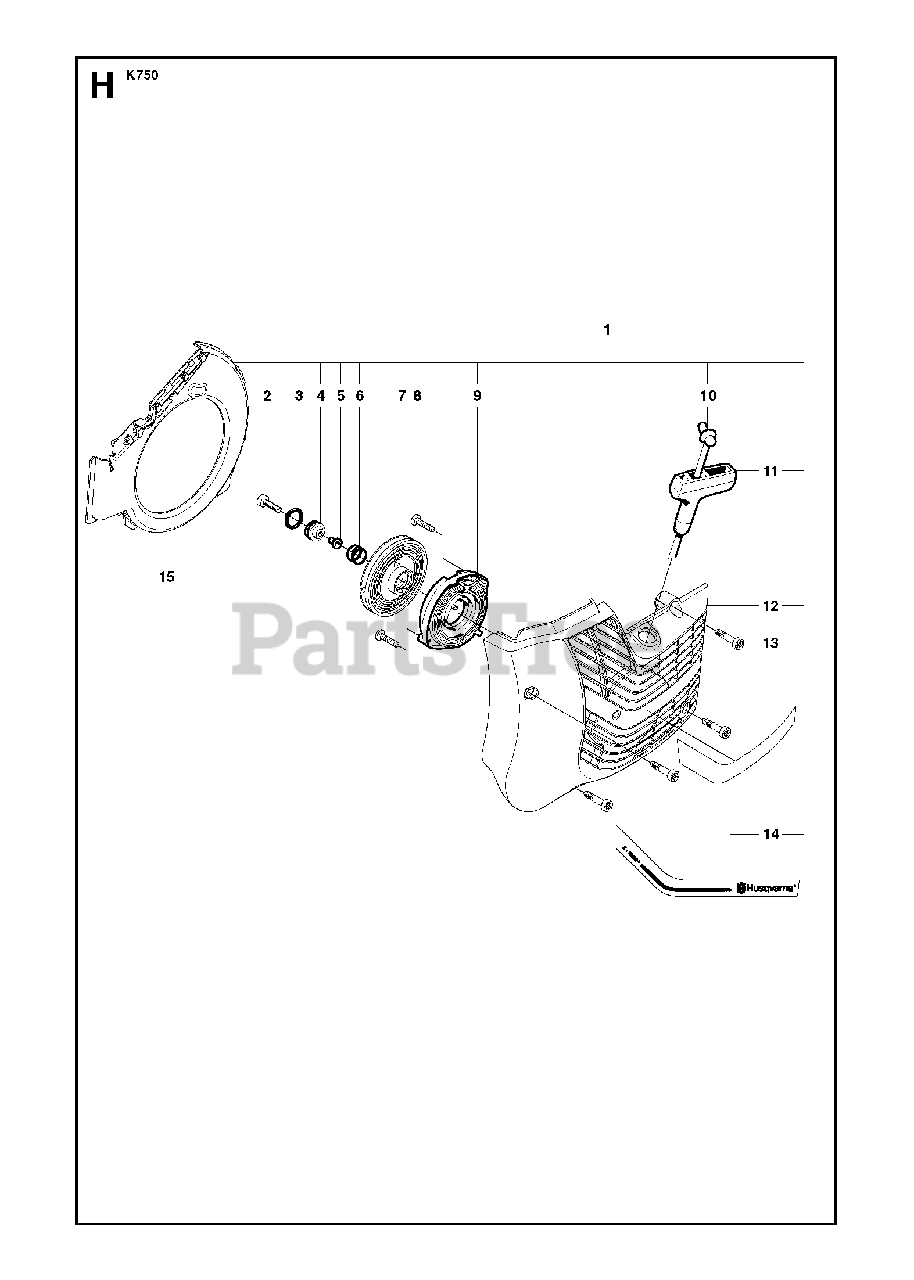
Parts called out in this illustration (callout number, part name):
1	STARTERIncl. 2 - 15
2	SCREW ITXSCT
4	GROMMET
5	SPACING SLEEVE
6	COMPRESSION SPRING
7	STARTER PULLEY
8	SCREW CCRPANT
9	RECOIL SPRING
10	STARTER CORD50 m
11	STARTER HANDLE
12	STARTER COVER
13	SCREW ITXSCM
15	AIR CONDUCTOR
